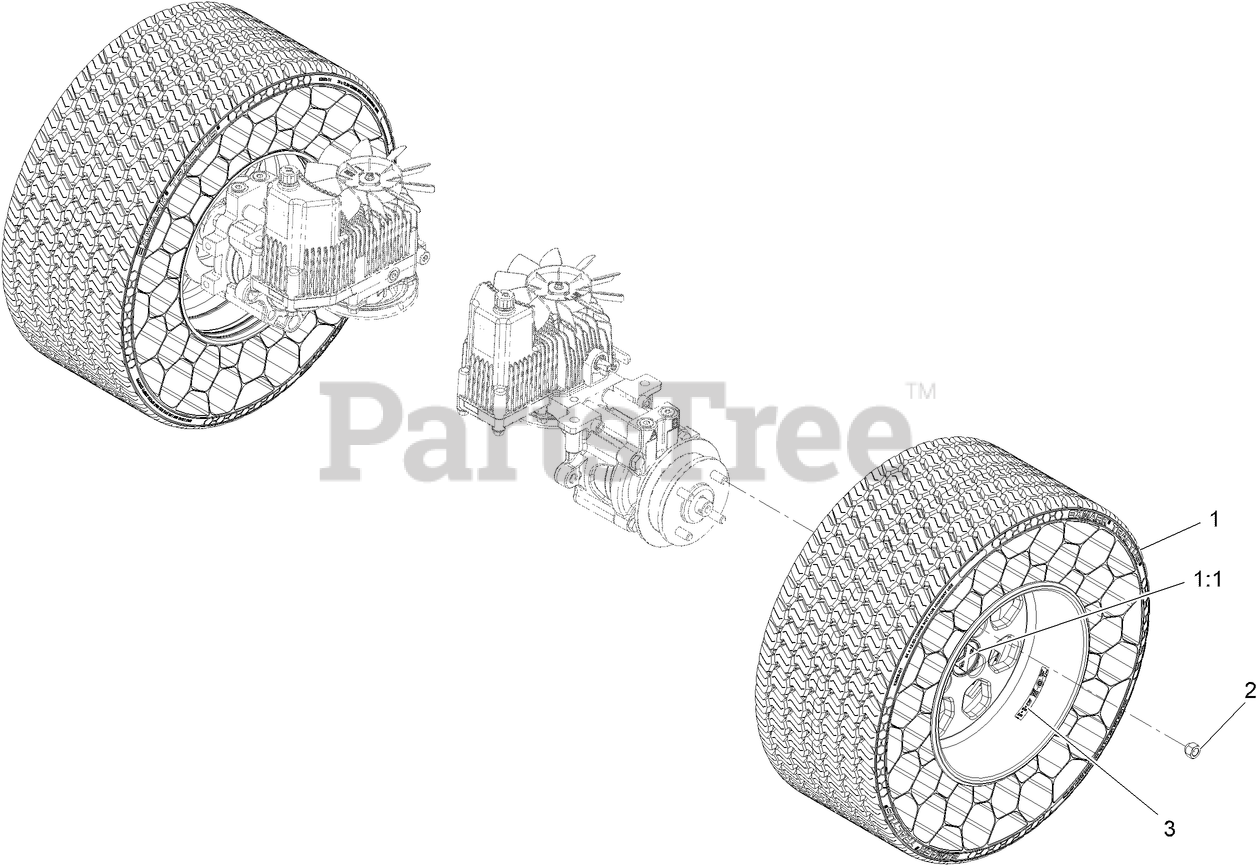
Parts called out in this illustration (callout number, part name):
1	Npt Wheel ASM
1:1	EXMARK NPT CAP BLK W/WHT LTR
2	NUT-LUG
3	DECAL-TORQUE, WHEEL HUB LUG
